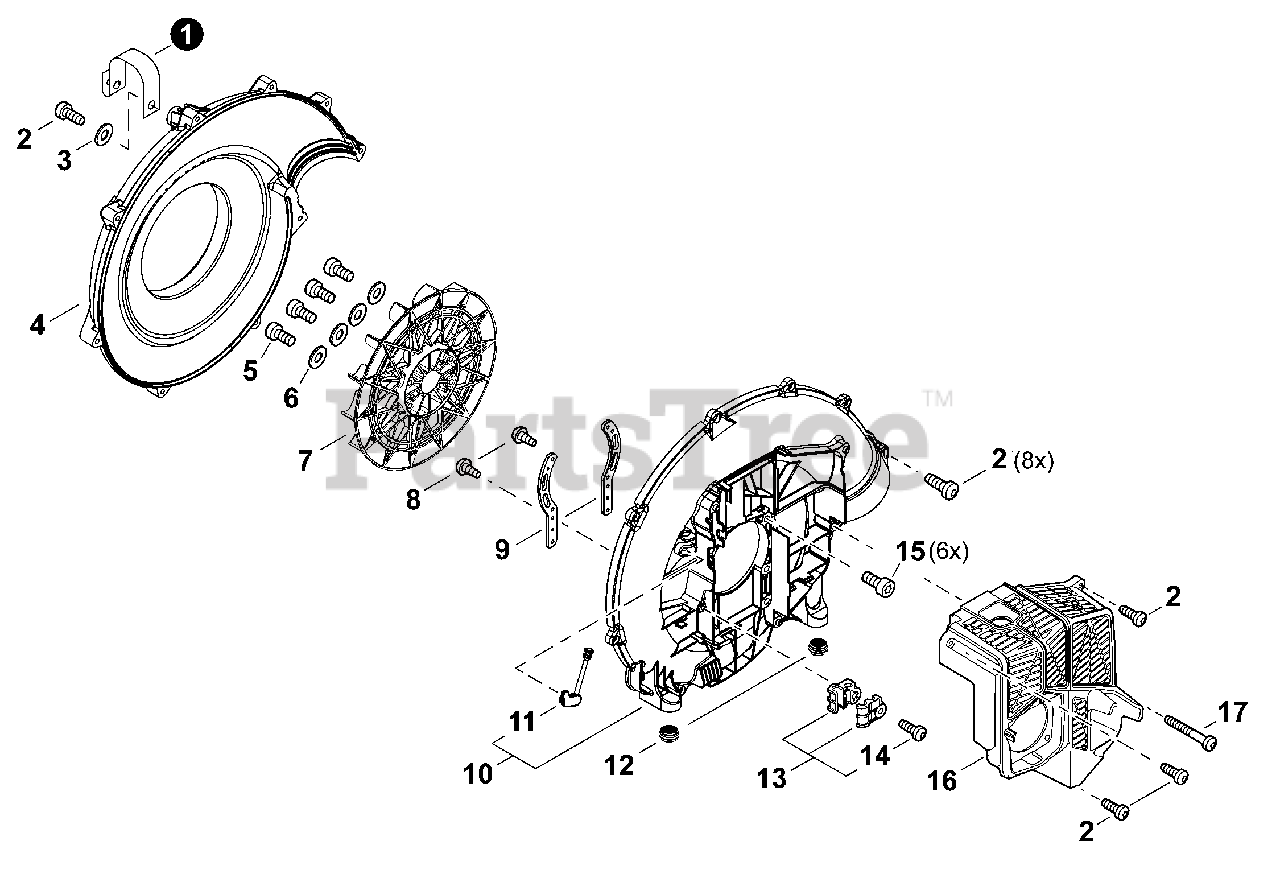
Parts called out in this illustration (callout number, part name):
1	STRAP, SAFETY 1.2×100
2	BOLT, TORX 5×20
3	WASHER 5.5×16×2T
4	COVER, FAN
5	BOLT, TORX 5×30
6	WASHER 5.5×16×2T
7	FAN, BLOWER
8	SCREW TAPPING 3×12
9	BRACKET, ENGINE
10	FAN CASE SET
11	GROMMET
12	CUSHION
13	CABLE HOLDER SET
14	BOLT, TORX 5×25
15	BOLT, TORX 5×30
16	COVER, ENGINE
17	BOLT, TORX 5×55
